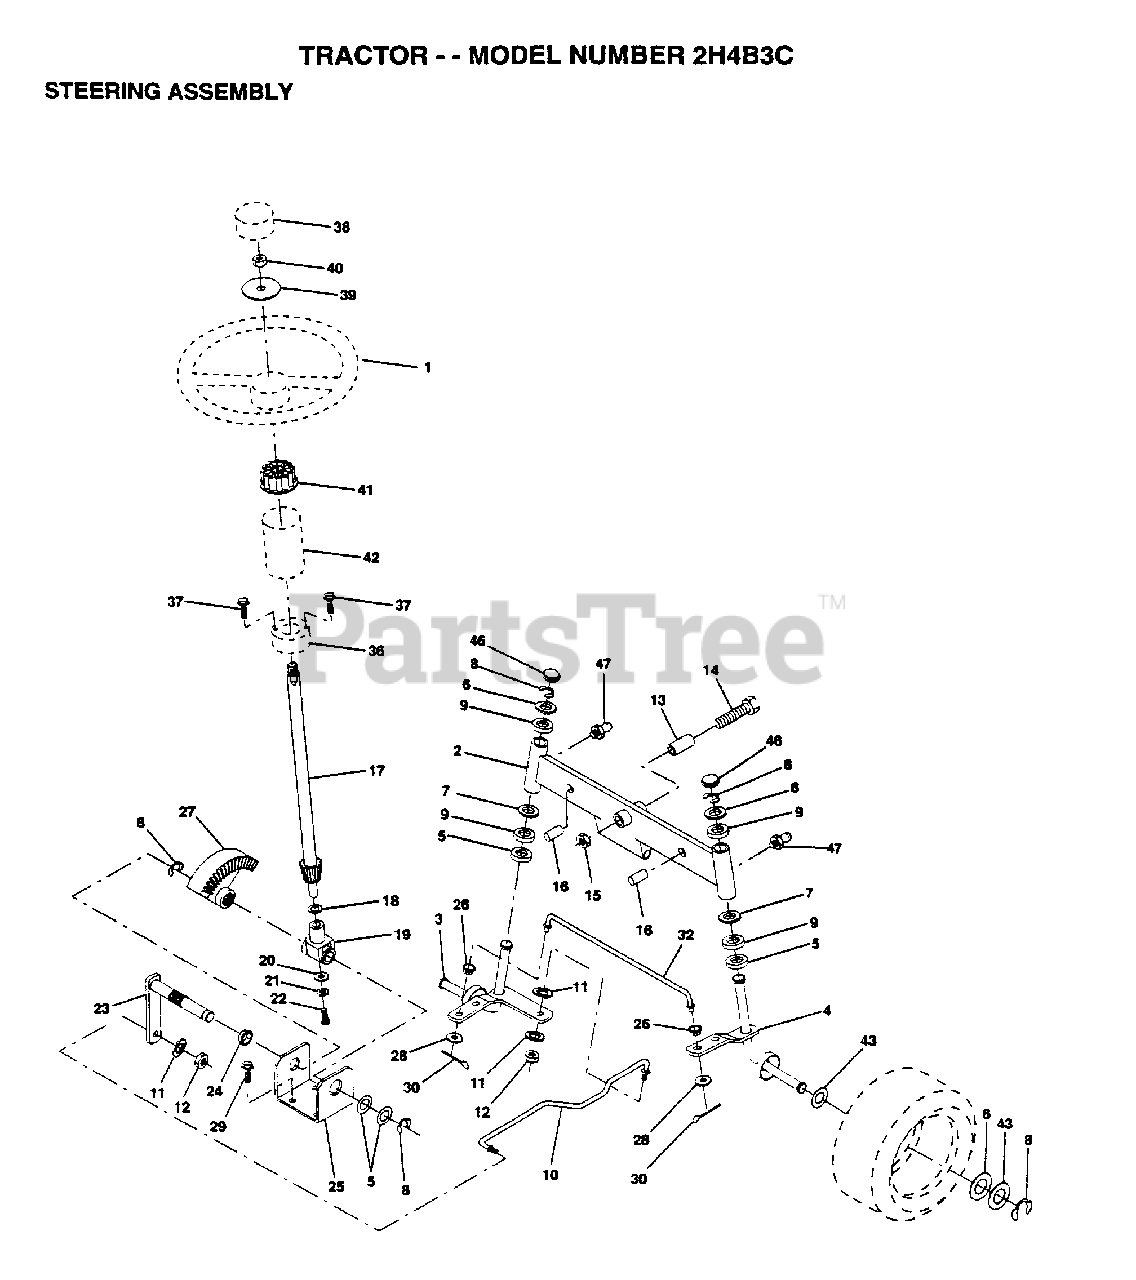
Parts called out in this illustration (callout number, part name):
2	AXLE ASM FRONT
3	SPINDLE LH
4	SPINDLE RH
5	WASHER .T
6	WASHER
7	WASHER
8	RING
9	COL. SRTG. BEAR.
11	LOCKWASHER
13	BEARING
14	BOLT HEX 5/8-11
16	AXLE PIN
17	SHAFT ASM
18	THRUST WASHER
19	SUPPORT.SHAFT
21	LOCKWASHER
22	"SCREW,SPECIAL"
24	NYLINER T
25	"BRKT,STEERING"
26	BUSHING.DRAGLINK
27	GEAR SECTOR
28	WASHER
29	SCREW
30	COTTER PIN
32	TIE ROD
38	ST WHL INSERT CAP
39	WASHER T
40	GRIPCO NUT
41	ADAPTER-WHEEL LT
42	"TUBE, STR SHAFT"
43	WASHER
46	CAP
47	ZERK M
